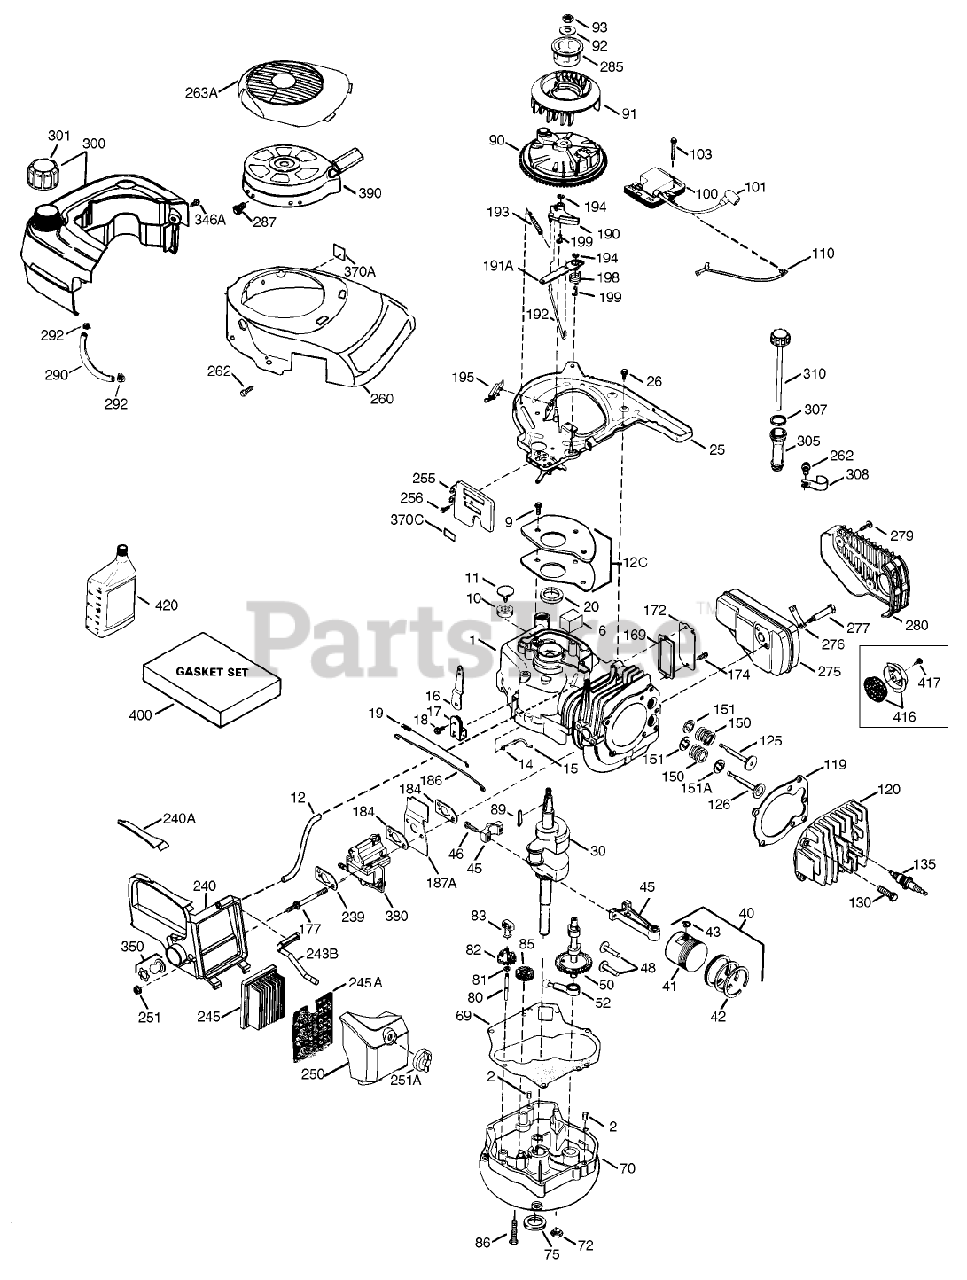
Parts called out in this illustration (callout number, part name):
1	Cylinder (Incl. 2, 10, 12, 20 125)
2	Pin-Dowel
6	Breather Element
9	Screw
10	Breather Valve Body
11	Check Valve
12	Breather Tube
12C	Breather Cover Gasket
14	Washer-Flat
15	Governor Rod (Machined)
16	Governor Level
17	Clamp-Lever, Governor
18	Screw (T-15, 8-32 x 19/64)
19	Governor Spring
20	Oil Seal
25	Blower Housing Baffle (Incl. 195)
26	Screw (1/2-20x5/8)
30	Crankshaft
40	Piston, Pin and Ring Set (STD)
40	Piston, Pin and Ring Set (.010 O S)
41	Piston Pin Ass-y.(Std.)(Incl. 43)
41	Piston Pin Ass-y.(.010 OS)(Incl.43)
42	FITTING - TANK 3/4"
42	FITTING - TANK 1"
43	Ring-Retaining, Piston Pin
45	Connecting Rod Ass-y. (Incl. 46)
46	Bolt-Rod, Connecting
48	Valve Lifter
50	Camshaft (MCR)
52	Oil Pump ASM
69	Mounting Flange Gasket
70	Mounting Flange (Incl. 72 thru 85)
72	Plug-Oil
75	Oil Seal
80	Shaft-Governor
81	Washer-Flat
82	Governor Gear ASM
83	Spool-Governor
85	Idler Gear
86	Screw, 1/4-20x1-9/16"
89	Flywheel Key
92	Washer-Belleville
93	Nut-Flywheel
100	Solid State Ignition (Incl. 101)
101	Cover-Spark Plug
103	Screw (T-15, 10-24 x 15/16)
110	Tine Bolt
119	Cylinder Head Gasket
120	Cylinder Head
125	Exhaust Valve (Std.)(Incl. 151)
125	Valve-Exhaust (1/32 O S)
126	Intake Valve (Std.)(Incl. 151)
126	Valve, Intake (1/32" oversize)(Incl. No. 40)
130	Screw (5/16-18x1-1/2)
135	Spark Plug-Resistor (R J19 L M)
150	Spring-Valve
151	Cap-Valve, Spring
151A	Seal-Valve, Intake
169	Gasket-Cover, Valve
172	Cover-Valve
174	Screw (10-24 x 9/16)
177	Carburetor Mounting Stud
184	Carburetor To Intake Pipe Gasket
186	Governor Link
187A	Air Baffle
190	Brake Lever ASM
191A	Brake Control Lever
192	Brake Control Lever Link
193	Brake Spring
194	Retaining Ring
195	Terminal
198	Brake Control Lever Spring
199	Brake Lever Bushing
239	Carburetor To Air Cleaner Gasket
240	Air Cleaner Body
240A	Air Cleaner Body Extension
243B	Air Cleaner Stud
245	Air Cleaner Filter
245A	Air Cleaner Filter
250	Air Cleaner Cover
251	Lock Nut, 1/4-20
251A	Wing Nut, 1/4-20
255	Control Plate
256	Screw, 8-32 x 21/64"
260	Blower Housing
262	Screw (1/4-20 x 1/2)
263A	61743/9557984/39151
275	Muffler
276	Locking Plate
277	Screw, 5/16-18 x 2-11/32"
279	Screw, Torx T-25, 12-24 x 49/64"
280	32076/VAR.W/32076/7
285	Starter Cup
287	Screw (8-32 x 21/64)
290	Fuel Line
292	Clamp-Line, Fuel
300	Fuel Tank (Incl. 301)
301	Cap-Fuel
305	Oil Fill Tube
307	O-Ring
308	Fill Tube Clip
310	Dipstick
346A	Screw (10-32 x 35/64)
350	Primer
370A	Decal-Lubrication
370C	Primer Decal
380	Carburetor (Incl. 187B 239 of Engine Parts List)
390	Rewind Starter ASM
400	Gasket Set (Incl. Items Marked PK in Notes) 0 Incl. part #-s 27234A (1),28833 (1), 36005A (1), 36032A (1), 36061 (1), 37136 (1), 696088 (1)
416	Spark Arrestor Kit (Incl. 417)(Optional)
417	Screw (10-32 x 1/2)
420	4 Cycle Oil, SAE 30 (Quart)
